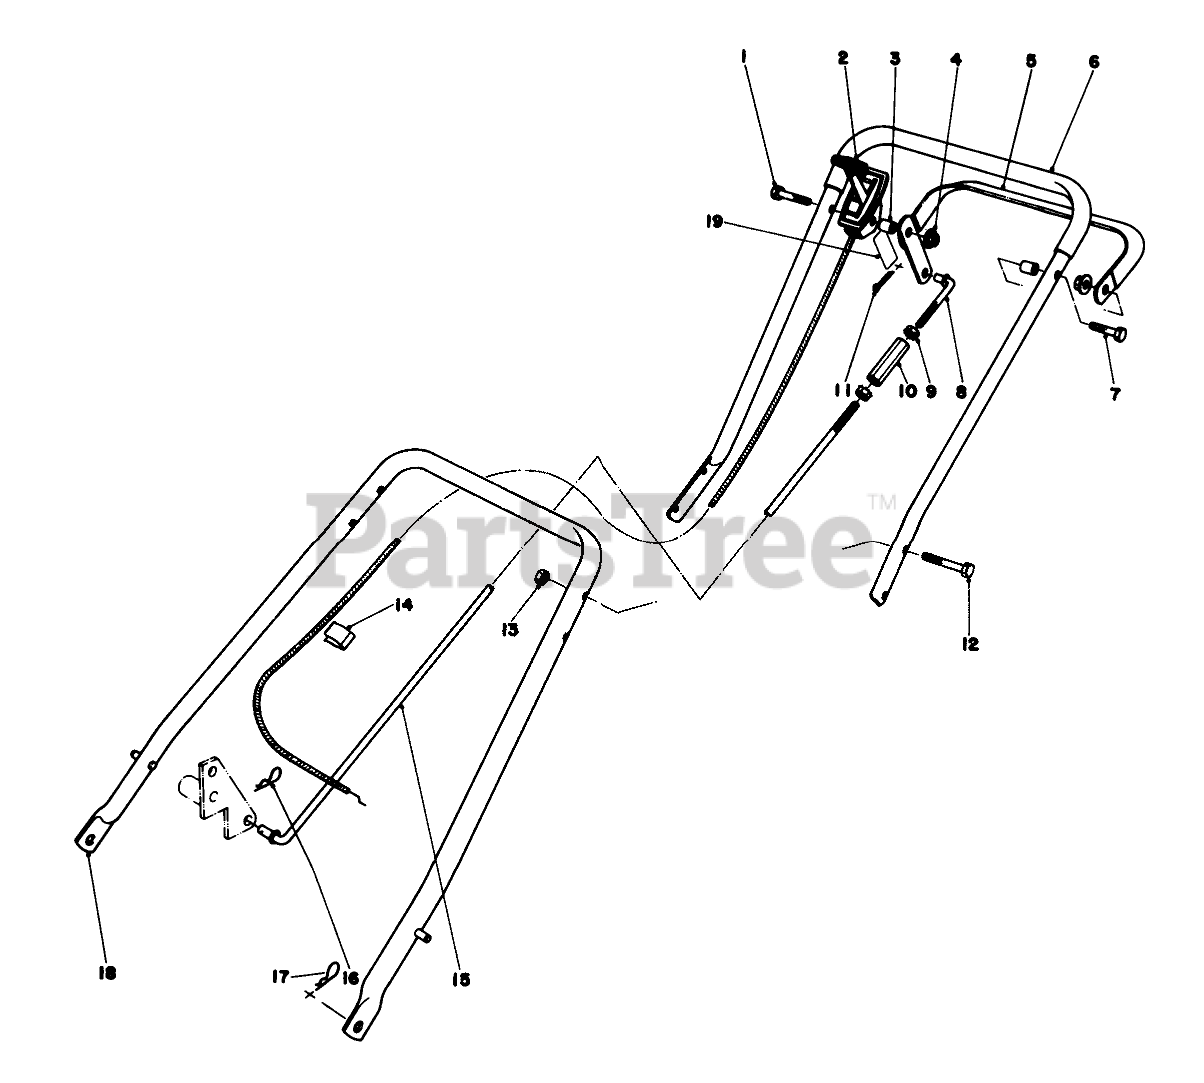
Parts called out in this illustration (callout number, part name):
1	SCREW-HH
2	THROTTLE CONTROL
3	Spacer
4	NUT-LOCK, HHF
5	Control Bail (Incl. Ref. #19)
6	UPPER HANDLE
7	SCREW-HH
8	LINK CONTROL ROD
9	NUT-KEPS
10	CONTROL ROD SLEEVE
11	PIN-COTTER
12	SCREW-HH
13	NUT-LOCK
14	Clamp
15	Rod Control
16	HAIRPIN COTTER
17	PIN-COTTER, HAIR
18	LOWER HANDLE WA
19	Decal Traction Control
